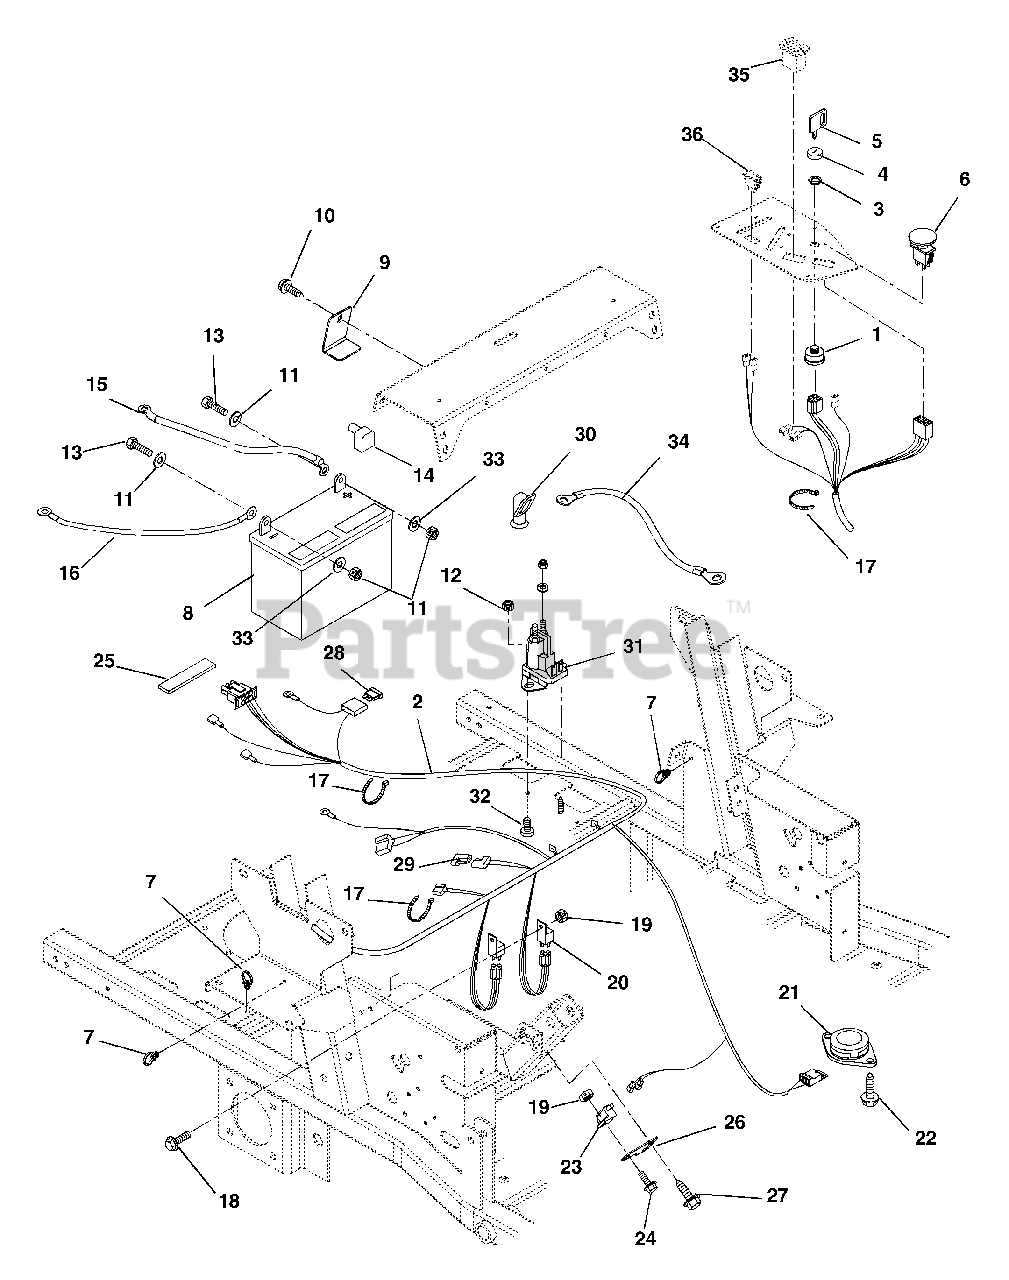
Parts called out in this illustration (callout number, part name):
1	SWITCH KEY 5Y463A ALT GRDNG
2	HARNESS, Z 6-PIN WIRING
3	NUT- PANEL .562-24 GRECO
4	CAP - IGNITION SWITCH
5	KEY -W/CAP
6	SWITCH, CLUTCH
7	TUBE CLIP 3/4 (4158)
8	BATTERY W/ TUBE
9	CLAMP, BATTERY HOLD DOWN
10	@SCR-TAP .25-20X.50 HWH TR YWZ
11	@WSHR-FL-STL.281X.62X.065 YWZC
12	@NUT-HEX .25-20 YWZC
13	@BLT-HEX .25-20X.75 GR5 YWZC
14	INSULATOR
15	START CABLE 22"
16	GROUND CABLE .25X13.00X.31
17	CABLE TIE LG 5-1/2
18	@SCR-MCH 10-24X.50 HWH YWZC
19	@NUT-LK-NYL 10-24 W/INSRT YWZC
20	RELAY
21	SEAT SWITCH
22	@SCR-TAP 12-24X.50 HWH TR YWZC
23	SWITCH- SINGLE POLE N.O.
24	@SCR-MCH 10-24X.75 HWH YWZC
25	PAD,BATTERY
26	PLATE - SWITCH
27	@SCR-TAP .38-16X.50 HWH TR YWZ
28	FUSE, 30 AMP.
29	MOLDED DIODE PLUG 1 AMP
30	BOOT, INSULATOR
31	SOLENOID
32	@BLT-HEX .25-20X.50 GR5 YWZC
33	@WSHR-LK .25X.062 REG YWZC
34	STARTER CABLE 6.75"
35	HOUR METER
36	LIGHT,INDICATOR
